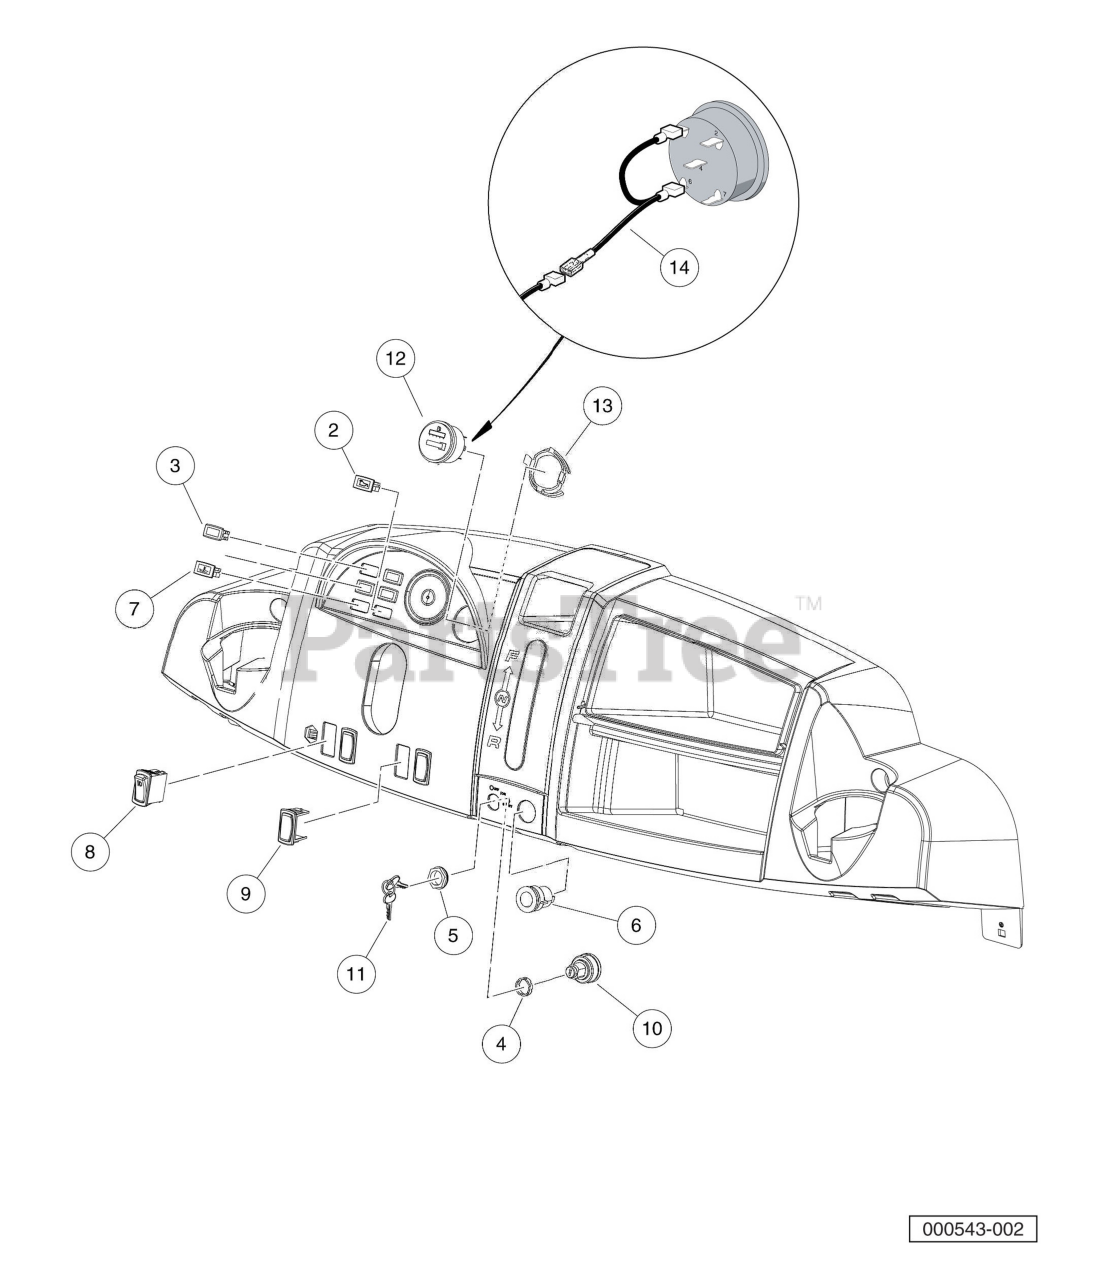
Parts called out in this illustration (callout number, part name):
1	Instl, Elec Sys, Restyle Diesl
2	Light, Oil
3	Plug, Hole
4	Spacer, Keyswitch
5	Nut, Key Switch
6	Receptacle, Accessory
7	Light, Indicator, Coolant Temp
8	Switch, Rocker, Light
9	Cover, Hole, Switch, Rocker
10	Keyswitch, 12v, Diesel
11	Keys (set of 2)
12	Gauge Fuel-hour Sep Gnd
13	Clip, Meter, Round
14	Asm Wire Meter F-h Jumper
